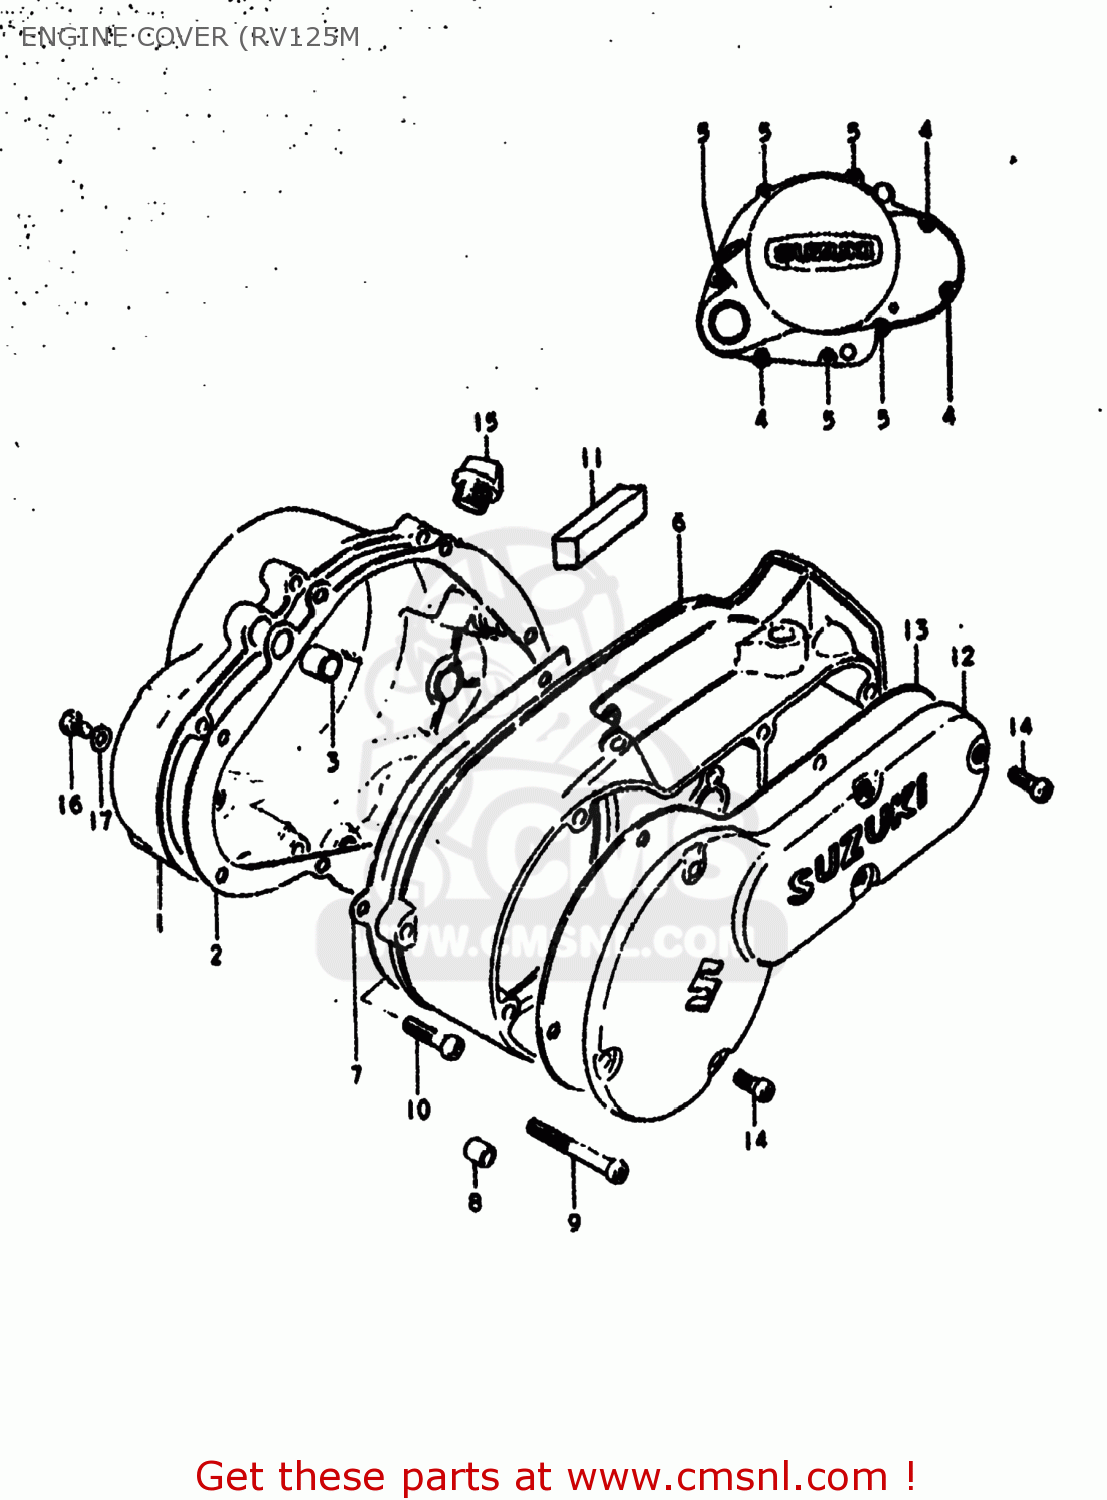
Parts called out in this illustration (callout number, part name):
1	COVER,CLUTCH
2	GASKET,CLUTCH COVER (MCA)
3	PIN
4	SCREW
5	SCREW
6	COVER,MAGNETO
7	GASKET,CLUTCH COVER (NAS)
8	PIN
9	SCREW
10	SCREW
11	SEAL,DUST
12	CAP,MAGNETO INSPECTION
13	GASKET,MAGNETO INSPECTION (MCA)
14	SCREW
15	PLUG
16	SCREW(6X10)
17	GASKET(6.2X11X1) (NAS)
